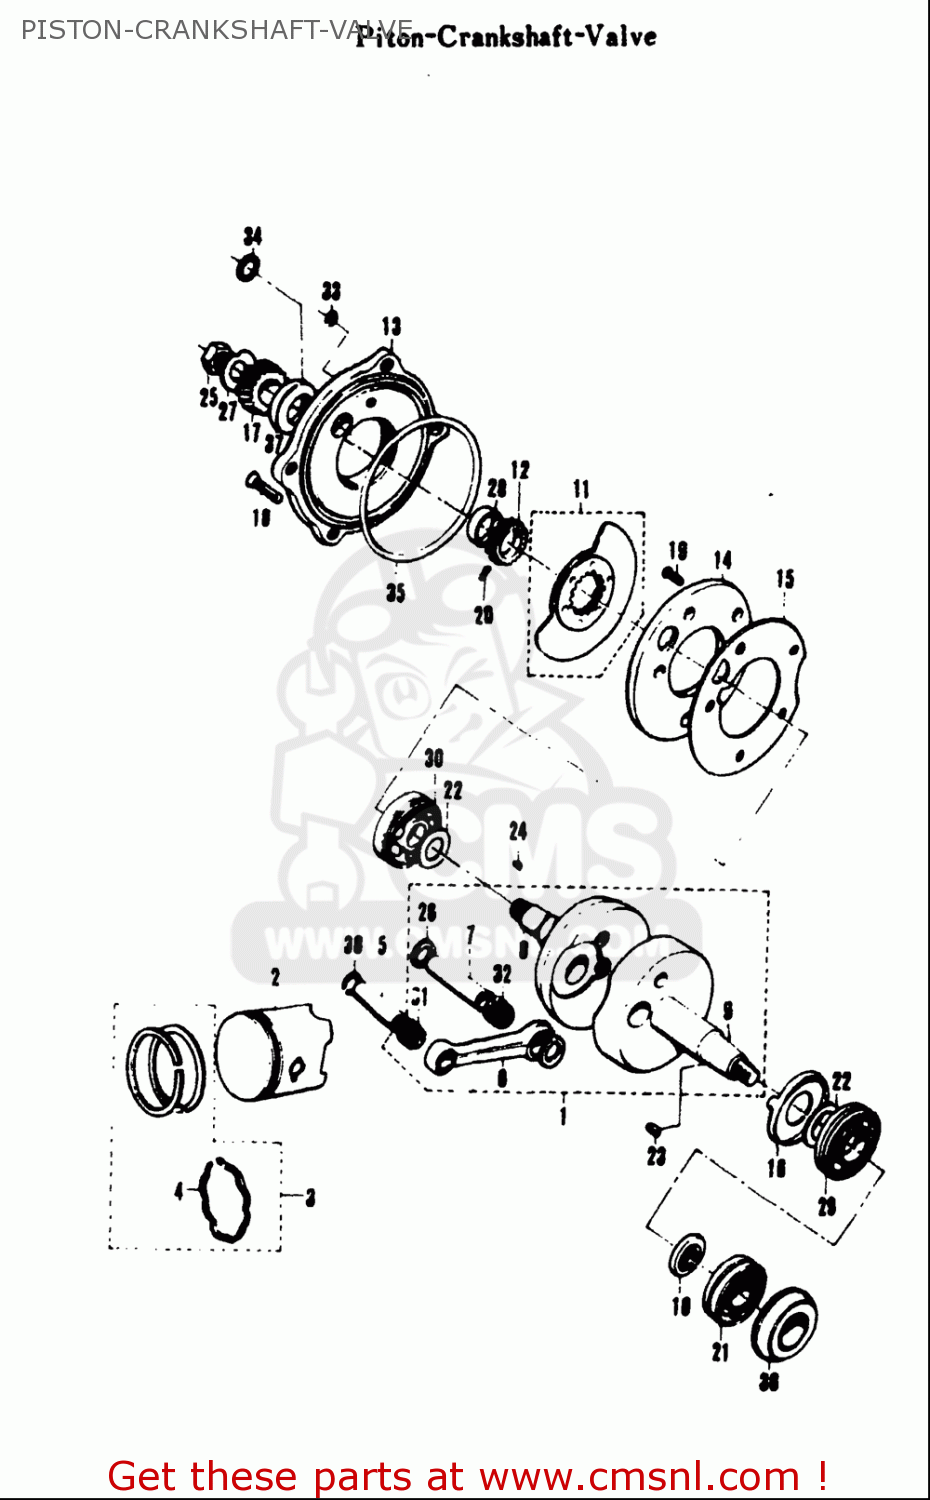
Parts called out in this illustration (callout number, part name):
2	PISTON
3	RING SET,PISTON
5	PIN,PISTON 14MM
6	ROD,CONNECTING
7	PIN,CRANK
13	SEAT,CRANK OUTER VALVE
20	PIN
21	BEARING(20X47X14)
22	SHIM(20X28X0.5)
23	KEY
24	KEY
25	NUT
26	WASHER(19X32X1)
29	BEARING(20X52X15)
30	BEARING(20X52X15)
31	BEARING(14X18X19.8)
32	BEARING(19X25X16)
33	O RING(D:1.5,ID:10)
34	O RING(D:1.5,ID:22.5)
35	O RING(D:2,ID:99)
36	SEAL,OIL(19.6X37X8)
37	OIL SEAL (25X44X7)
